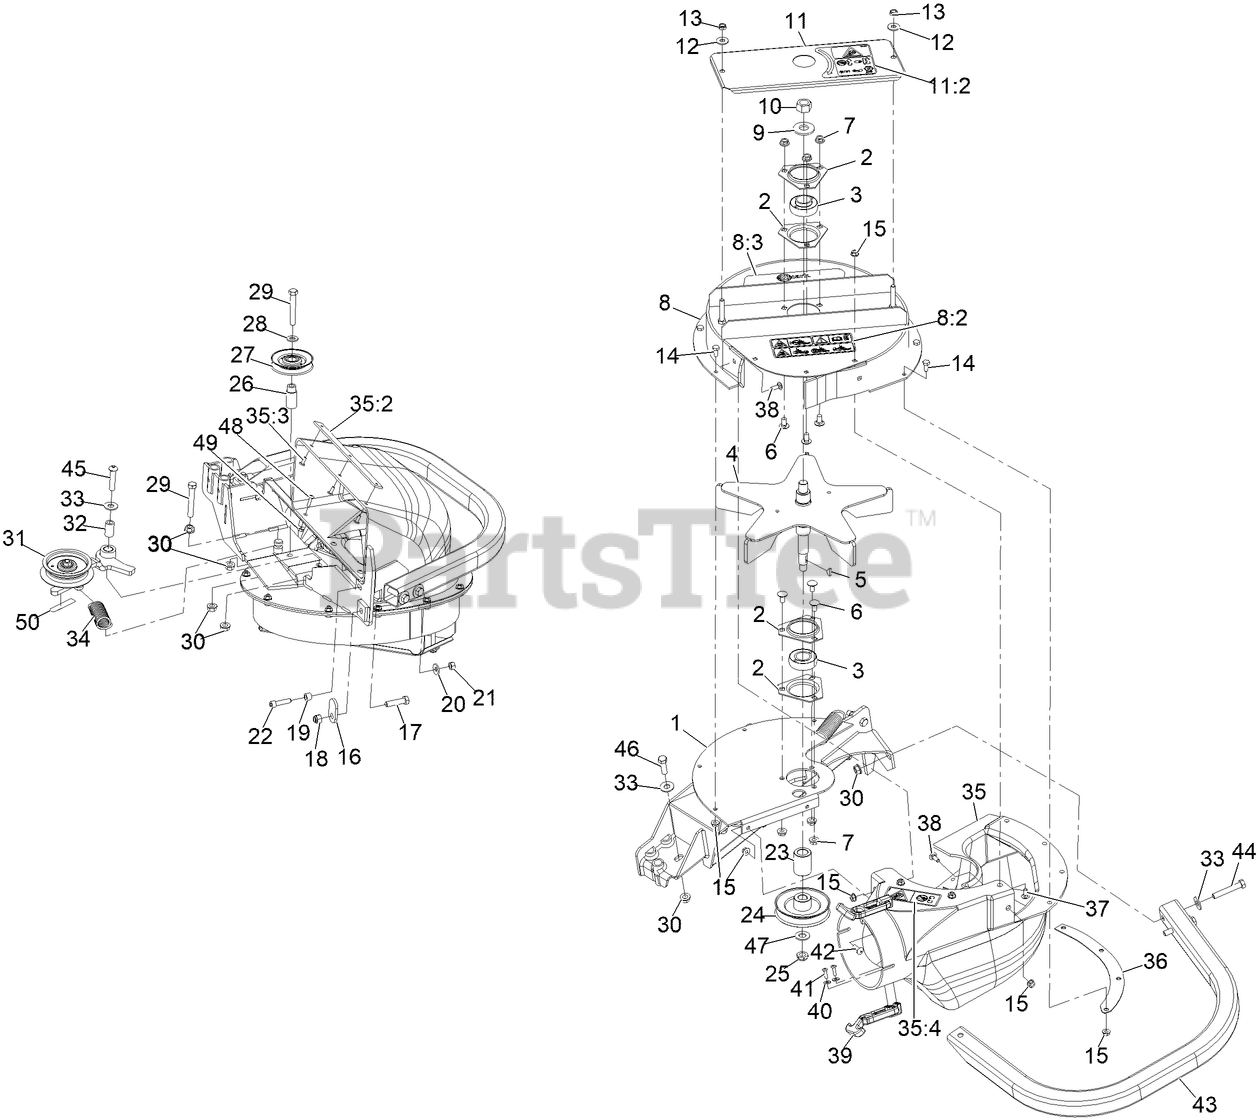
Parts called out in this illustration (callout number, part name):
1	Weld, Blower Frame
2	HOUSING-FLANGE
3	BEARING
4	IMPELLER
5	KEY-WOODRUFF
6	SCREW-CARR
8	UPPER-HOUSING W/DECAL
8:2	DECAL-ULTRAVAC S-SERIES
8:3	DECAL-WARNING
9	WASHER-SPRING
10	NUT-HEX
11	COVER-BEARING W/DECAL
11:2	DECAL-WARNING
12	WASHER-FLAT
13	NUT-LOCK, NI
14	SCREW-HH
16	LATCH-CATCHER, GRASS
17	SCREW-HH
18	NUT-LOCK, NI
19	BUSHING, LOCATOR
20	WASHER-SPRING
21	NUT-HEX
22	SCREW-HSH
24	SHEAVE-BLOWER
25	NUT-LOCK, NI
27	IDLER-INSIDE
28	WASHER-FLAT
29	SCREW-HH
30	NUT-HHF, WHIZ
31	ASM, IDLER
32	BUSHING-PIVOT, IDLER
33	WASHER-FLAT
34	SPRING-IDLER
35	ASM,BLOWER CHUTE LHP
35:2	PLATE-REINFORCEMENT
35:3	RIVET-BLIND
35:4	Decal-Blower-Impeller Hazard
36	PLATE-BACKING, BLOWER
37	SCREW-CARR
38	BOLT-CARR
39	LATCH-RUBBER
40	WASHER-FLAT
41	SCREW-PPH
44	SCREW-HH
45	SCREW-HSBH
46	SCREW-HH
47	WASHER-FLAT
48	SCREW-HEAD, TRUSS
50	DECAL-WARNING
